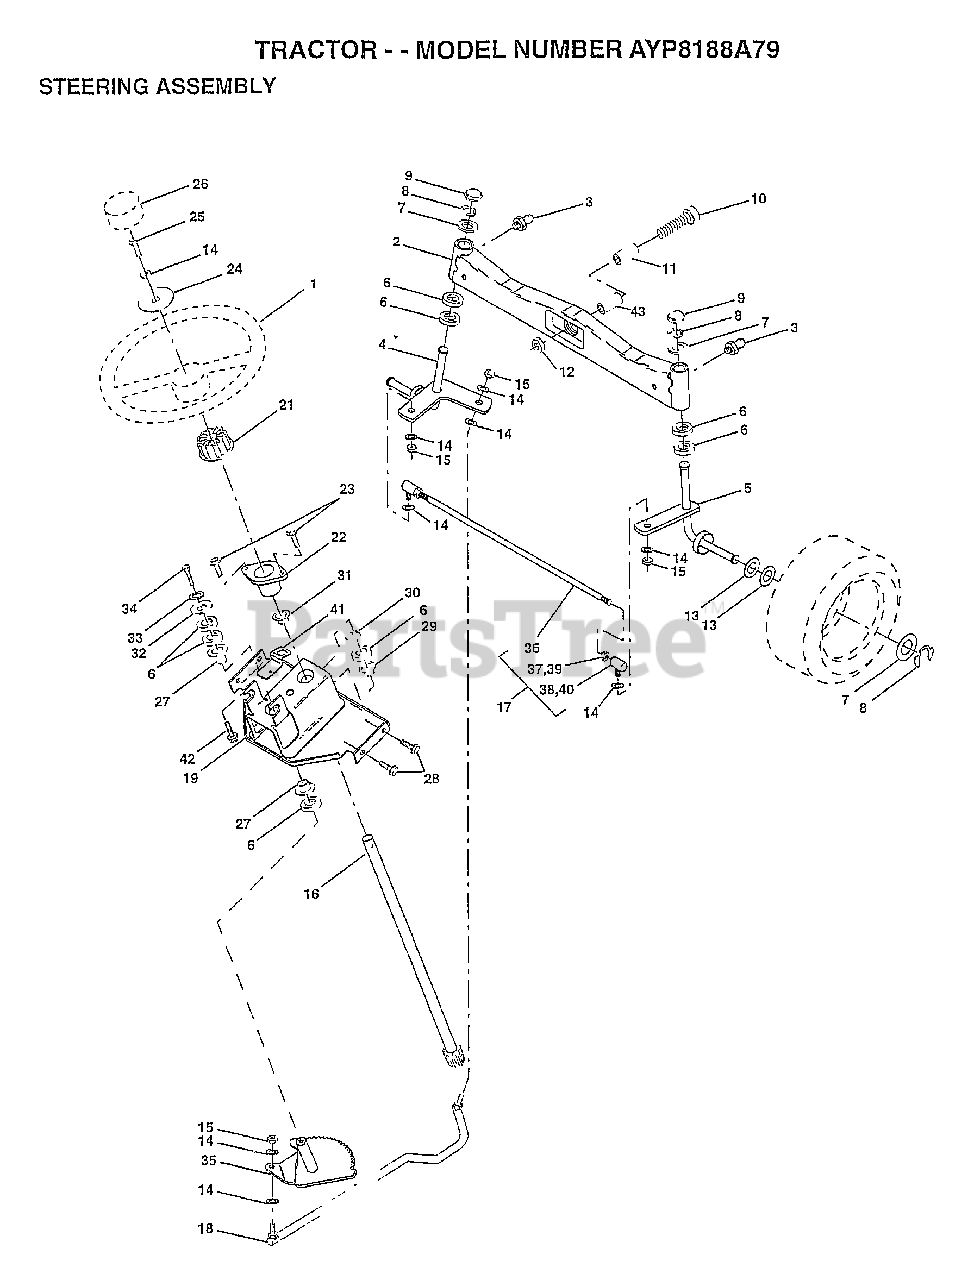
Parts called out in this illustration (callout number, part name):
3	ZERK M
4	SPINDLE.ASM.LH
6	WASHER .T
7	WASHER
8	RING
9	CAP
10	BOLT
11	BEARING AXLE
12	"NUT-LOC,FLANGE LT"
13	WASHER
14	LOCKWASHER
15	GRIPCO NUT
16	SHAFT.STEER.VGT
17	ROD.ASM.TIE.BALL
18	DRAGLINK.BALL.JOI
19	SUPPORT ASM-STEER
21	ADAPTER LT
22	"BUSHING,STEERING"
23	"SCREW-TT,10-32 FL"
24	WASHER T
25	BOLT
26	"INSERT,STR WHEEL"
27	COL. SRTG. BEAR.
28	SCREW
29	"FLANGE GT, BEAR."
30	KLIP RING
31	BUSHING.NYLINER.
32	WASHER
33	LOCKWASHER
34	BOLT
35	GEAR.ASM.SECTOR.
37	NUT
38	JOINT.RH
39	NUT
40	JOINT.LH
41	"BRKT-SW, INTER"
42	SCREW LT
43	SPACER AXLE
